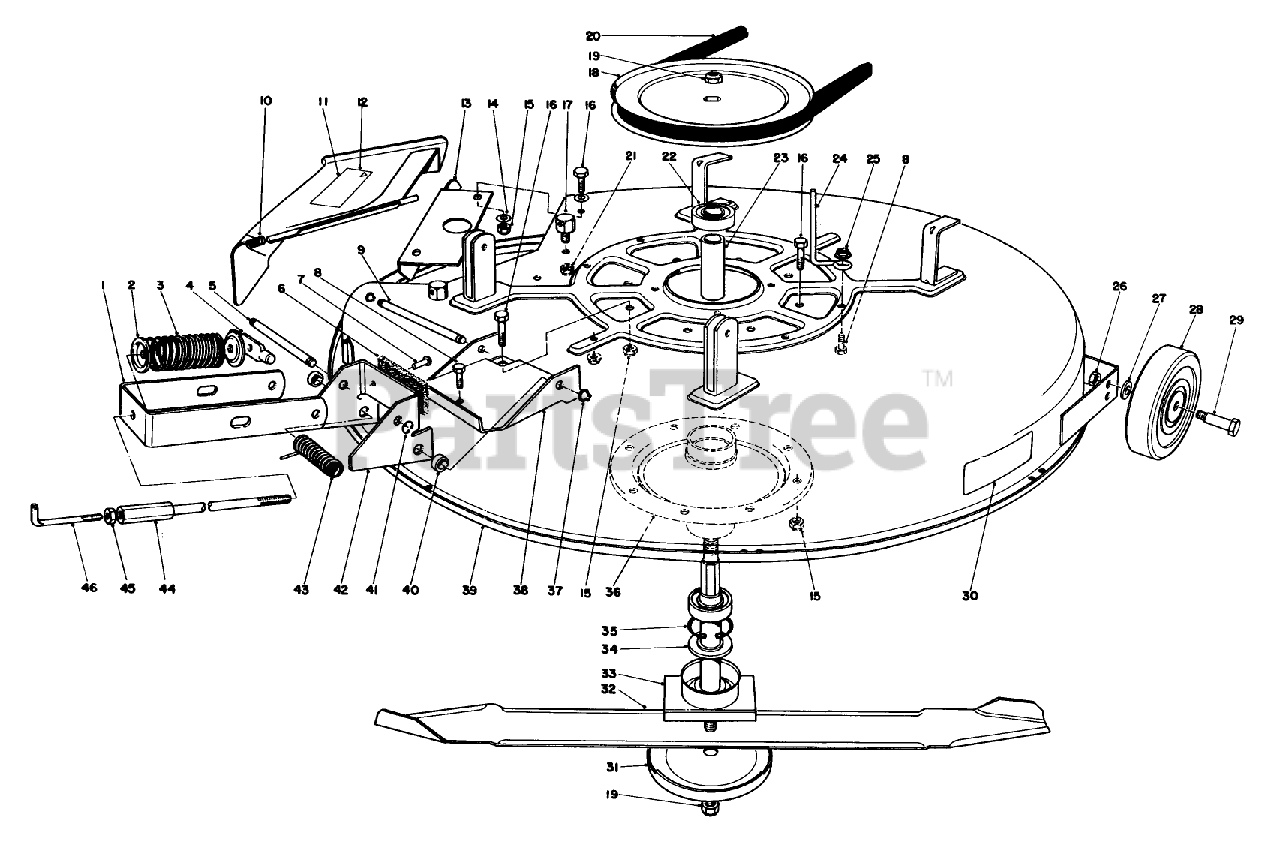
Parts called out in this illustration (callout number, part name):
1	Bracket-Engagement
2	RETAINER-SPR. TOP
3	SPRING-COMPRESSION
4	SHAFT-DECK ADJ.
5	Pin-Clevis
6	BRAKE PAD
7	RIVET .187 X 7/16 BRASS
8	SCREW-HH
9	CLEVIS PIN
10	SPRING
11	Deflector Assembly (Incl. Ref. #12)
12	Decal
13	Baffle Deck
14	WASHER-PLAIN
15	NUT-LOCK, NI
16	SCREW-HH
17	POST-PIVOT
18	PULLEY
20	V-BELT, DECK
21	NUT-LOCK, SIDE
22	BEARING-BALL
23	Spacer-Bearing
24	BELT GUIDE
25	NUT-LOCK, HHF
26	Nut
27	WASHER-FLAT
28	DECK WHEEL
30	DECK DECAL
31	Cup
32	Blade
33	SPINDLE SHAFT WA
34	SPACER-SPINDLE
35	RING-RETAINING
36	Spindle Body
37	RING-RETAINING
38	DECK ENGAGE CHANNEL R
39	Cutter Deck
40	DECK BRAKE SPACER
41	E-RING
42	Support Deck Brake Assembly (Incl. Ref. #6 & 7)
43	SPRING
44	ADJ HUB WA
45	NUT-JAM
46	ADJ. ROD
